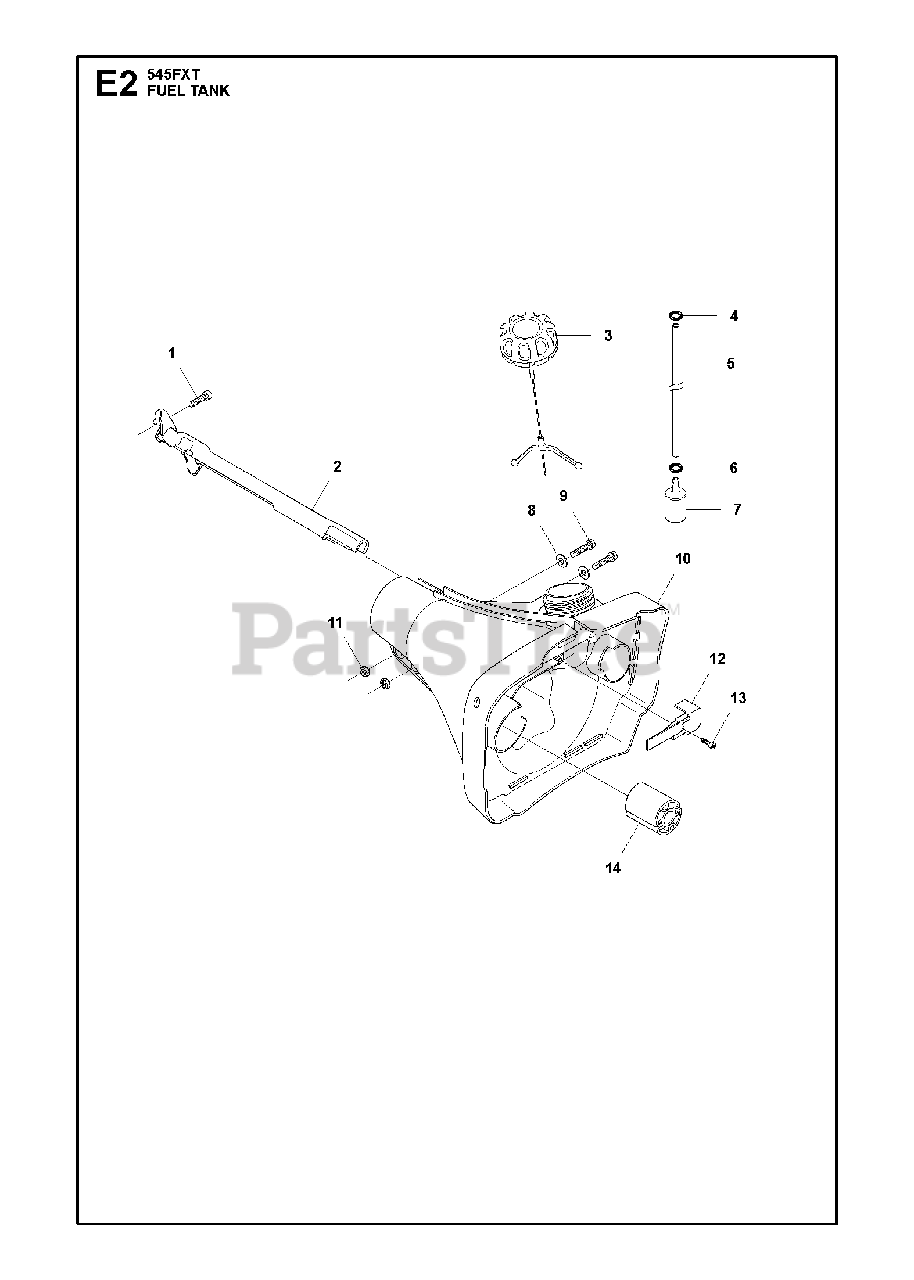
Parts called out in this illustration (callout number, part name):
2	PROTECTOR
3	%WINTER TANK CAP
5	FUEL HOSE STRAIGHT 265
7	FUEL FILTER
8	WASHER 5.3X12
10	TANK UNIT
13	SCREW
14	ANTIVIBRATION ELEMENT
